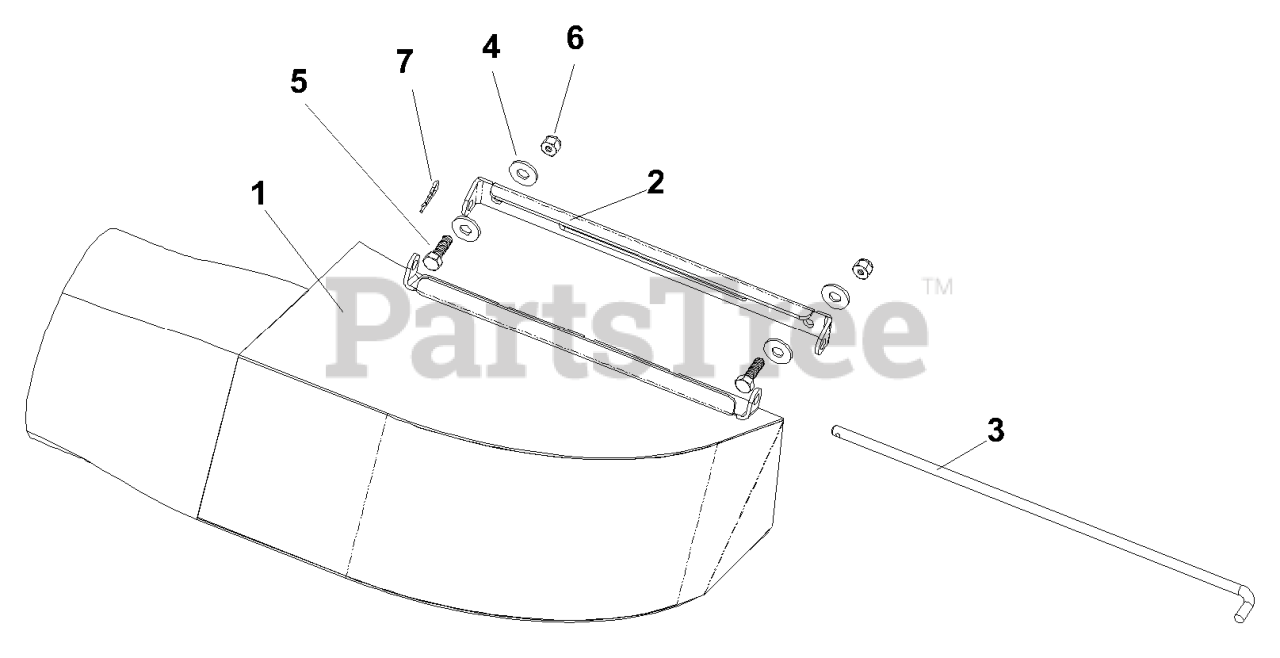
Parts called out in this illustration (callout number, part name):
1	Boot - Gen I
1	Boot - Gen II & Gen II - 72" deck
2	DECK BRACKET
3	BOOT ROD - 14"
4	Washer, 5/16
5	R/B 990209 BLT HEX 5/16-18 X 1
6	Nut, 51/6-18, nylock
7	PIN, HAIR COTTER #13 5/64 X 1
